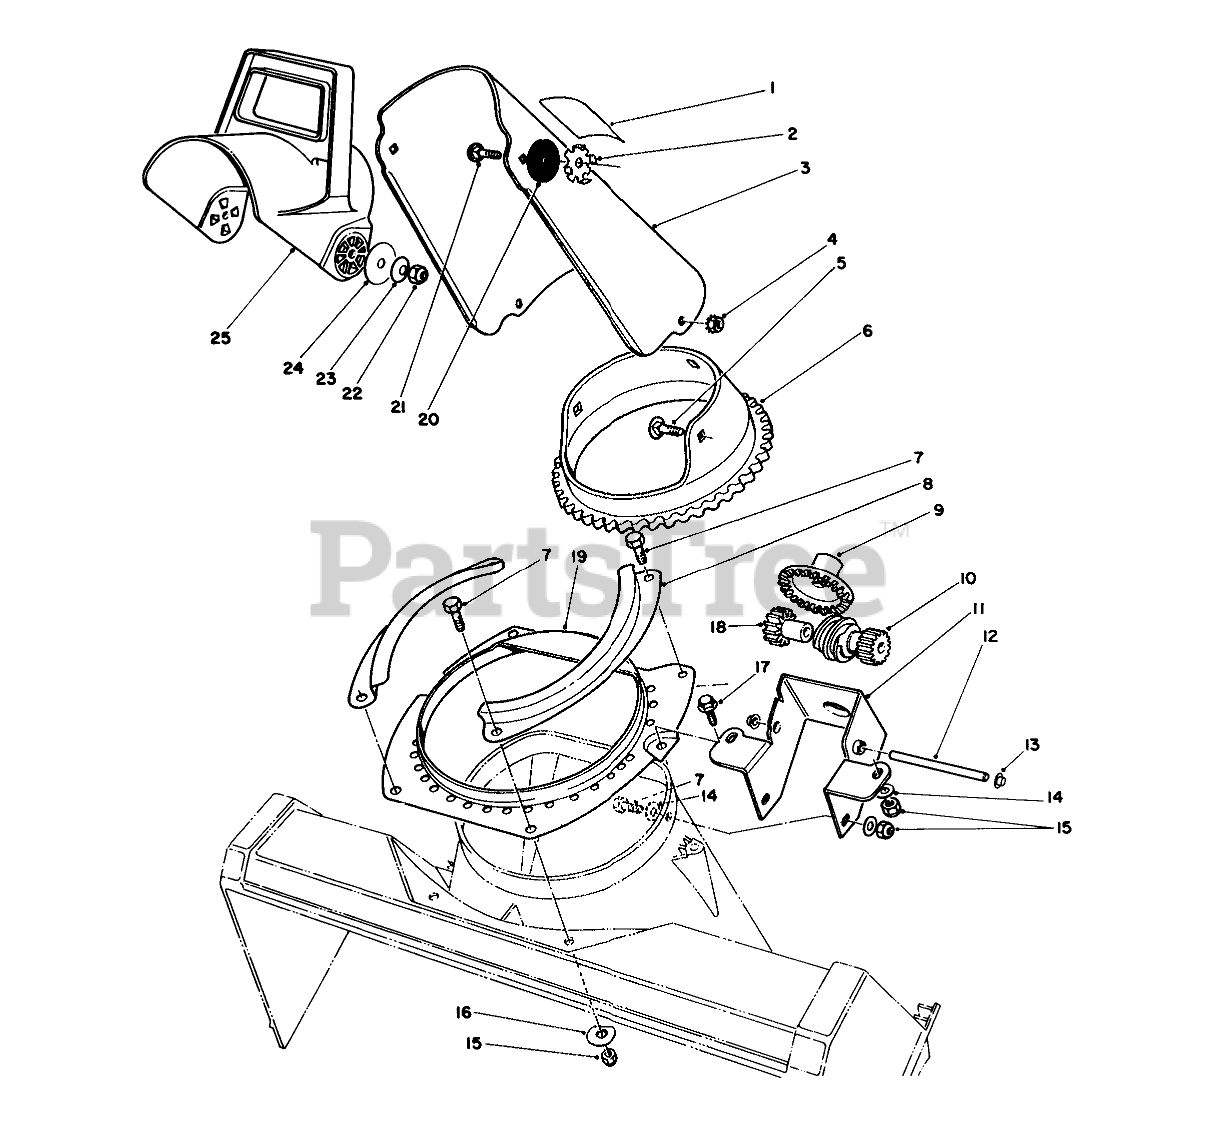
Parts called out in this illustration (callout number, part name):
1	Decal-Discharge
2	PLATE-FRICTION
3	Chute-Discharge
4	NUT-KEPS
5	SCREW-CARR
6	RING-GEAR, CHUTE
7	SCREW-HH
8	Retainer-Chute Ring
9	GEAR-FACE
10	GEAR-SPUR/WORM
11	Bracket-Chute Gears
12	SHAFT-GEAR, WORM
13	NUT-PUSH
14	WASHER-FLAT
15	NUT-LOCK, NI
16	Washer
17	SCREW-PLASTITE
18	GEAR-SPUR, SPACER
19	Ring-Chute Support
20	WASHER-RUBBER
21	SCREW-CARR
22	NUT-LOCK, NI
23	WASHER-BELLEVILLE
24	WASHER-FLAT
25	Deflector
